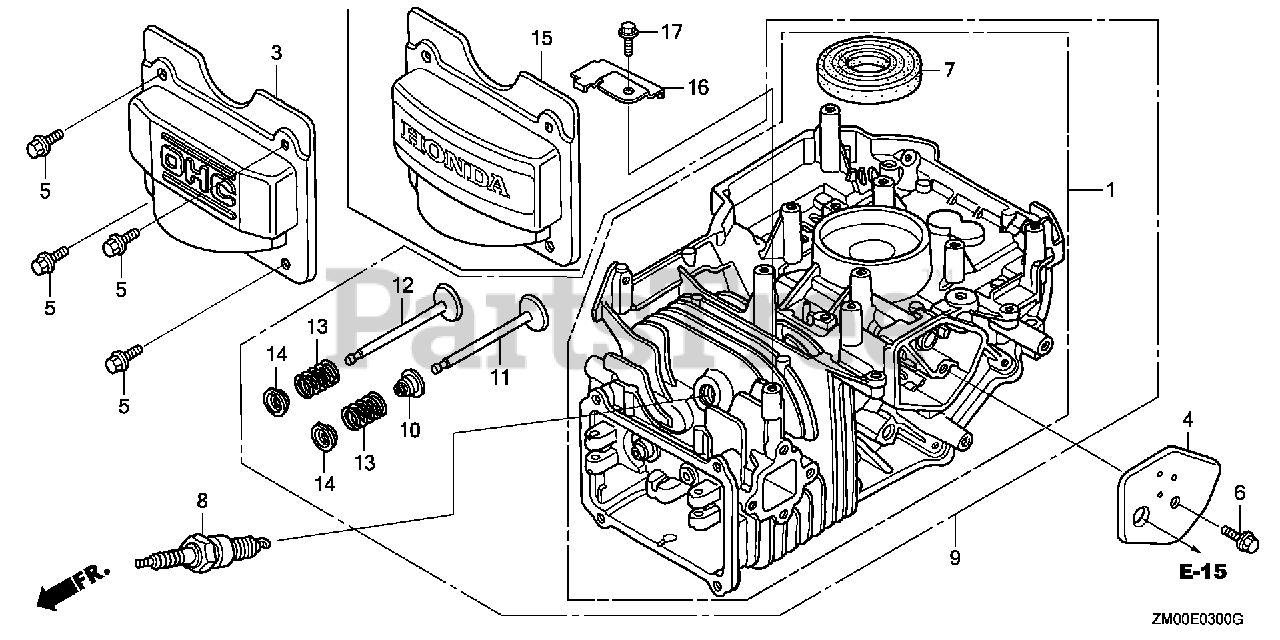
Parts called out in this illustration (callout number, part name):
1	CYLINDER ASSY.
3	COVER, CYLINDER HEAD
4	COVER, BREATHER (Honda Code 5580006). (BREATHER VALVE ASSY.)
5	BOLT, FLANGE (6X12) (CT200)
5	BOLT, FLANGE (6X13)
6	BOLT, FLANGE (6X14)
7	OIL SEAL (25.4X62X6)
8	SPARK PLUG (BPR6ES) (NGK)
9	CYLINDER ASSY.
10	SEAL, VALVE STEM
11	VALVE, IN. (TECHNOSTAR)
12	VALVE, EX. (L8E)
13	SPRING, VALVE
14	RETAINER, IN. VALVE SPRING
14	RETAINER, VALVE SPRING (EXHAUST SIDE)
